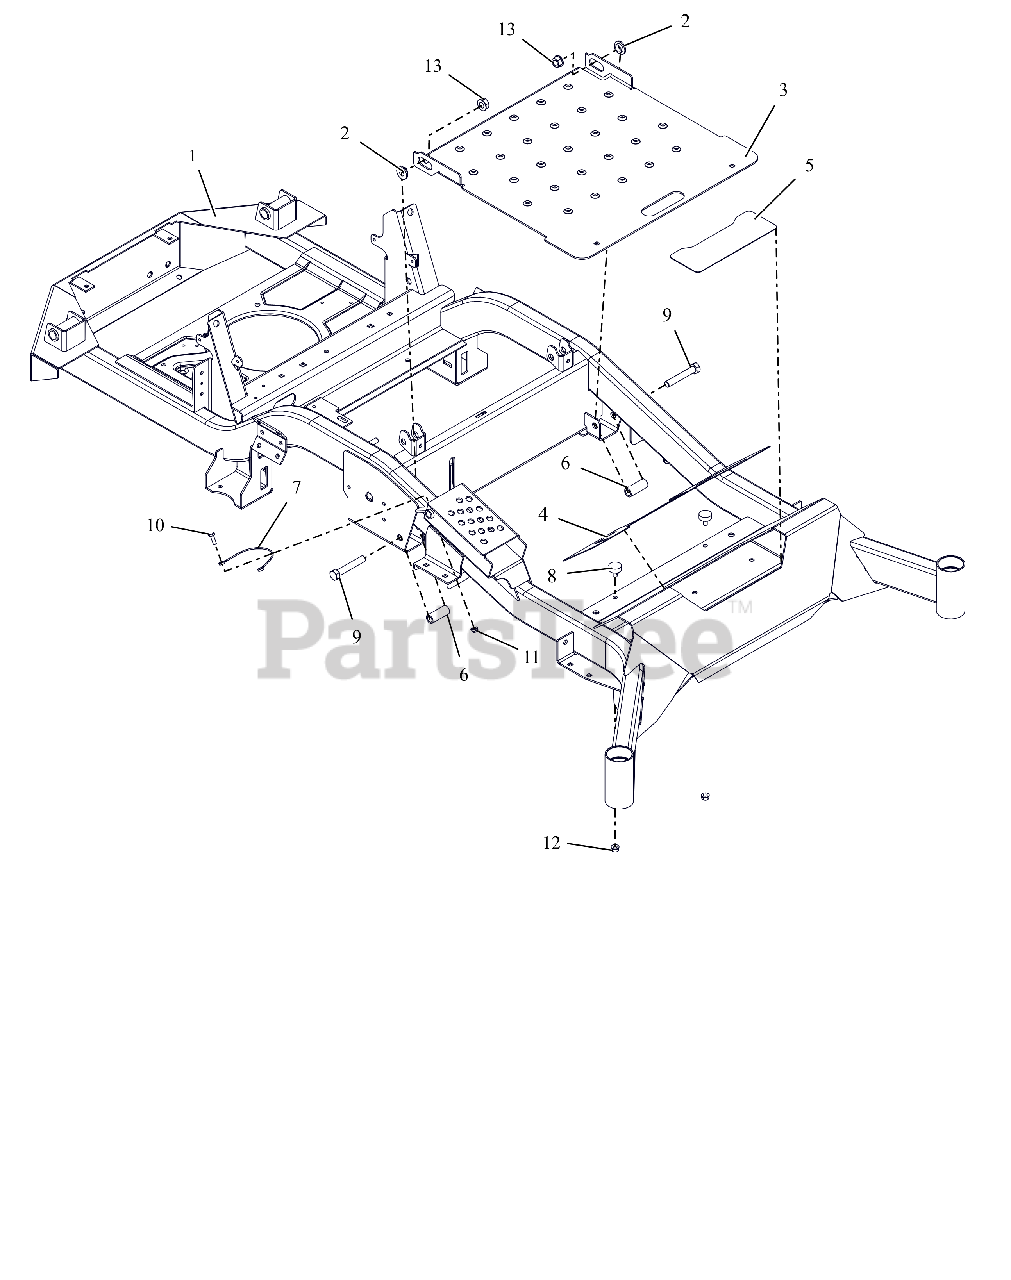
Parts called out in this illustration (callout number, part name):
1	APEX 60"FRAME W/SAFTETY DECALS
2	BSHG-FLG .515X.750X.395X1.120
3	PANEL, ACCESS
4	GRIP, FRONT
5	GRIP, STEP
6	SPACER, .515X.75X1.83
7	CABLE, 12.0 LANYARD, NYLON
8	BUMPER, RUBBER
9	BLT, HEX .50-13X3.00 G5 ZCC
10	BLT, HEX .25-20X.75 G5 ZCC
11	NUT,NYL-FLG .25-20 GF ZCC
12	NUT,SPNLK-FLG .31-18 G5 ZCC
13	NUT,FLG-TOP LK .625-11 FBP
